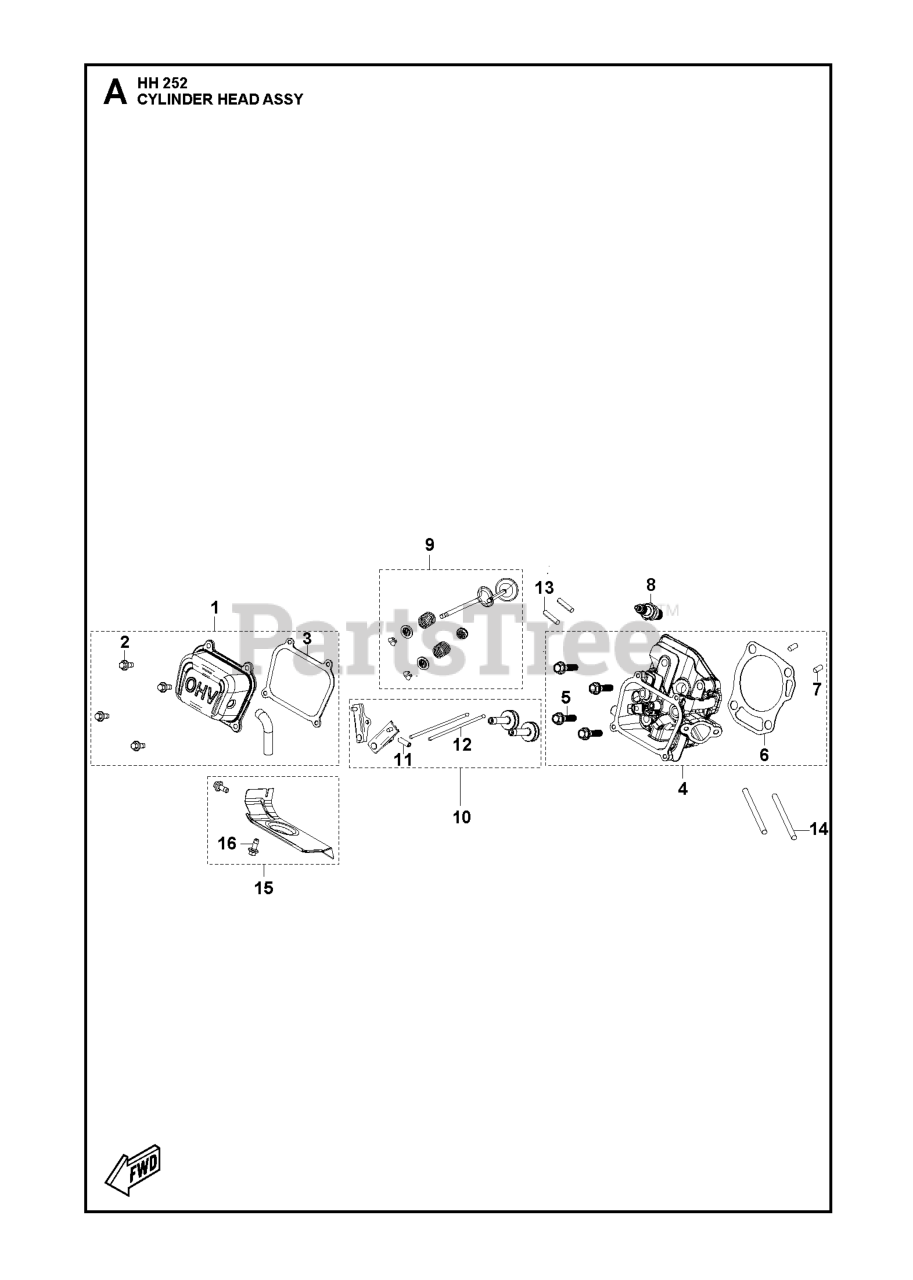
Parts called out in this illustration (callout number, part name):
1	CYLINDER COVER CYLINDER HEAD C
3	GASKET CYLINDER HEAD COVER GAS
4	CYLINDER HEAD KIT
6	GASKET CYLINDER HEAD GASKET
7	PIN LOCATION PIN
8	SPARK PLUG HQT-7 RESISTOR
9	VALVE KIT
10	VALVE KIT ROCKER ARM KIT
11	PLATE PUSH ROD GUIDE PLATE
12	PUSH ROD PUSH ROD SET
15	DEFLECTOR AIR DEFLECTOR KIT
16	BOLT
